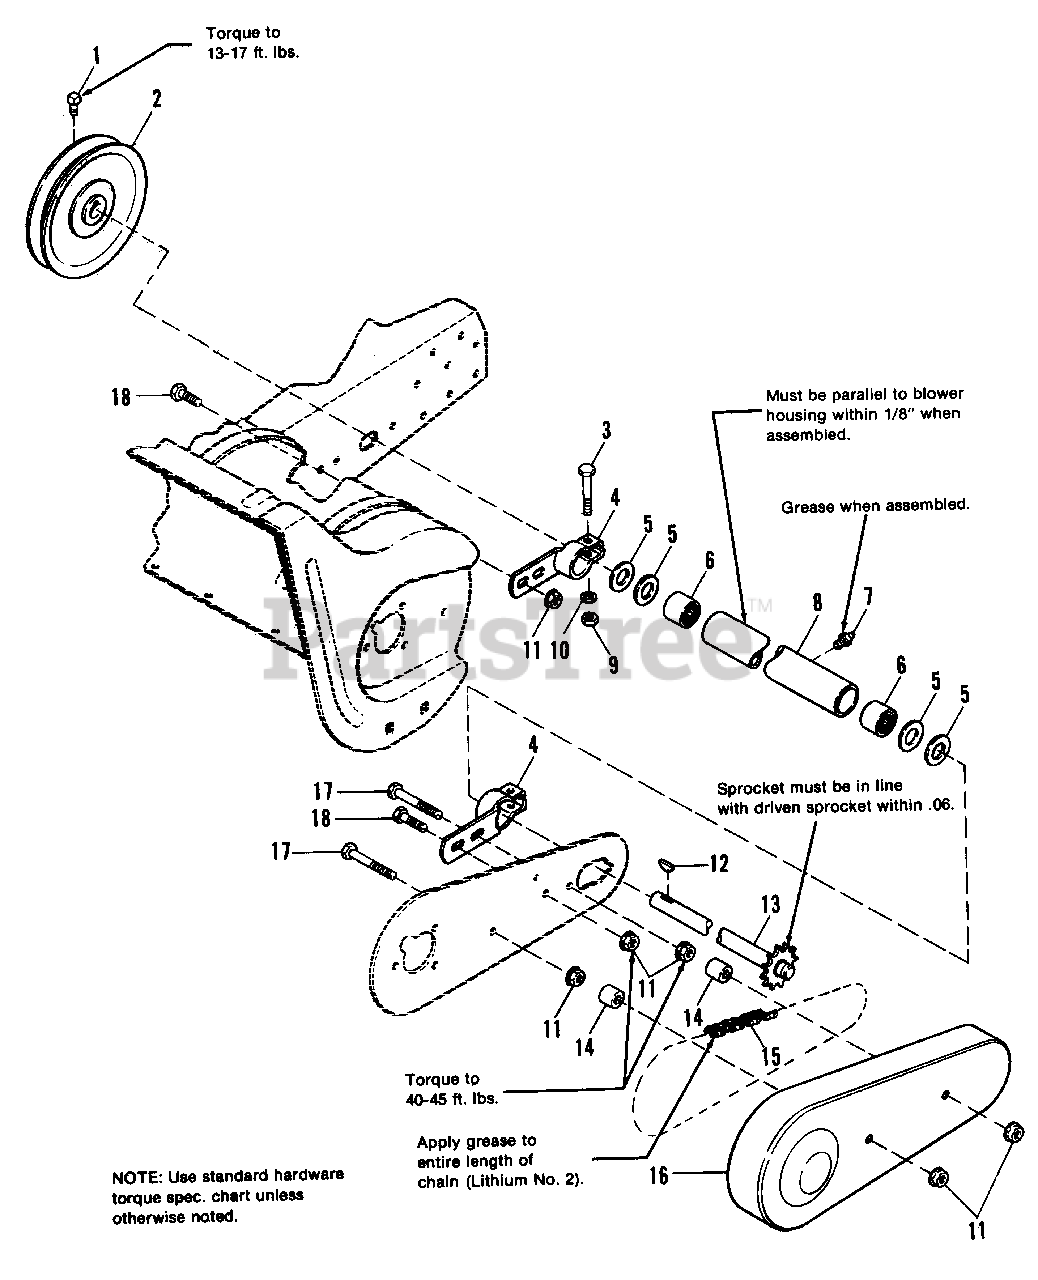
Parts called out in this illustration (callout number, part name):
1	SETSCREW, 5/16-18 x 1/2
3	CAPSCREW, Hex, 5/16-18 x 1-3/4
6	BEARING, Needle
7	FITTING, Grease
8	HOUSING ASSY., w/Bearings (1690547 Only)
8	HOUSING ASSY., w/Bearings (1690548 Only)
9	NUT, Hex, Full, 5/16-18
10	LOCKWASHER, 5/16
11	LOCKNUT, Flange, 3/8-16
12	KEY
13	SHAFT ASSY. (1690547 Only)
13	SHAFT ASSY. (1690548 Only)
15	CHAIN (Auger Drive)
16	GUARD, Chain
17	SCREW, Hex, Whizlock, 3/8-16 x 2-1/4
18	SCREW, Hex, Whizlock, 3/8-16 x 1
